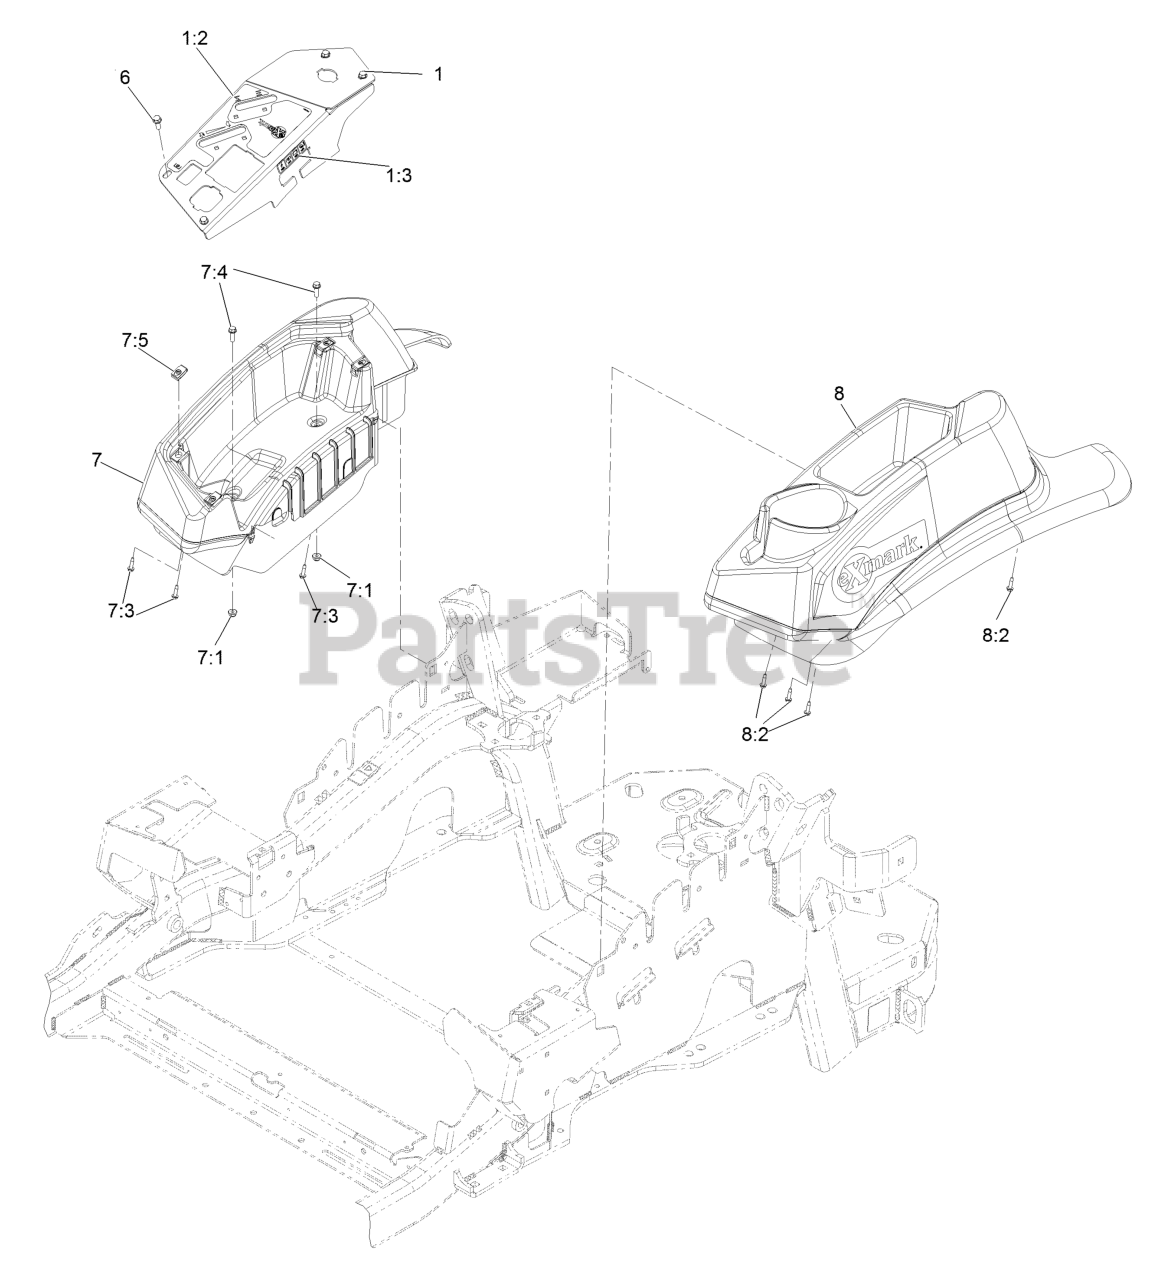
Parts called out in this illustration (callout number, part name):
1	ASM-Panel, Control W/Decal
1:2	Decal-Control Panel Non-Efi
1:3	Decal-Fuses
6	Screw-Machine 1/4-20 X 3/4
7	Console,RH Narrow ASM
7:1	Nut-Nyloc 1/4-20 Flg
7:3	Screw-HWH #10-14 X 3/4 Tf
7:4	Screw-Machine 1/4-20 X 3/4
7:5	Nut-Retainer-Panel 1/4-20
8	Console.LH Narrow ASM
8:2	Screw-HWH #10-14 X 3/4 Tf
